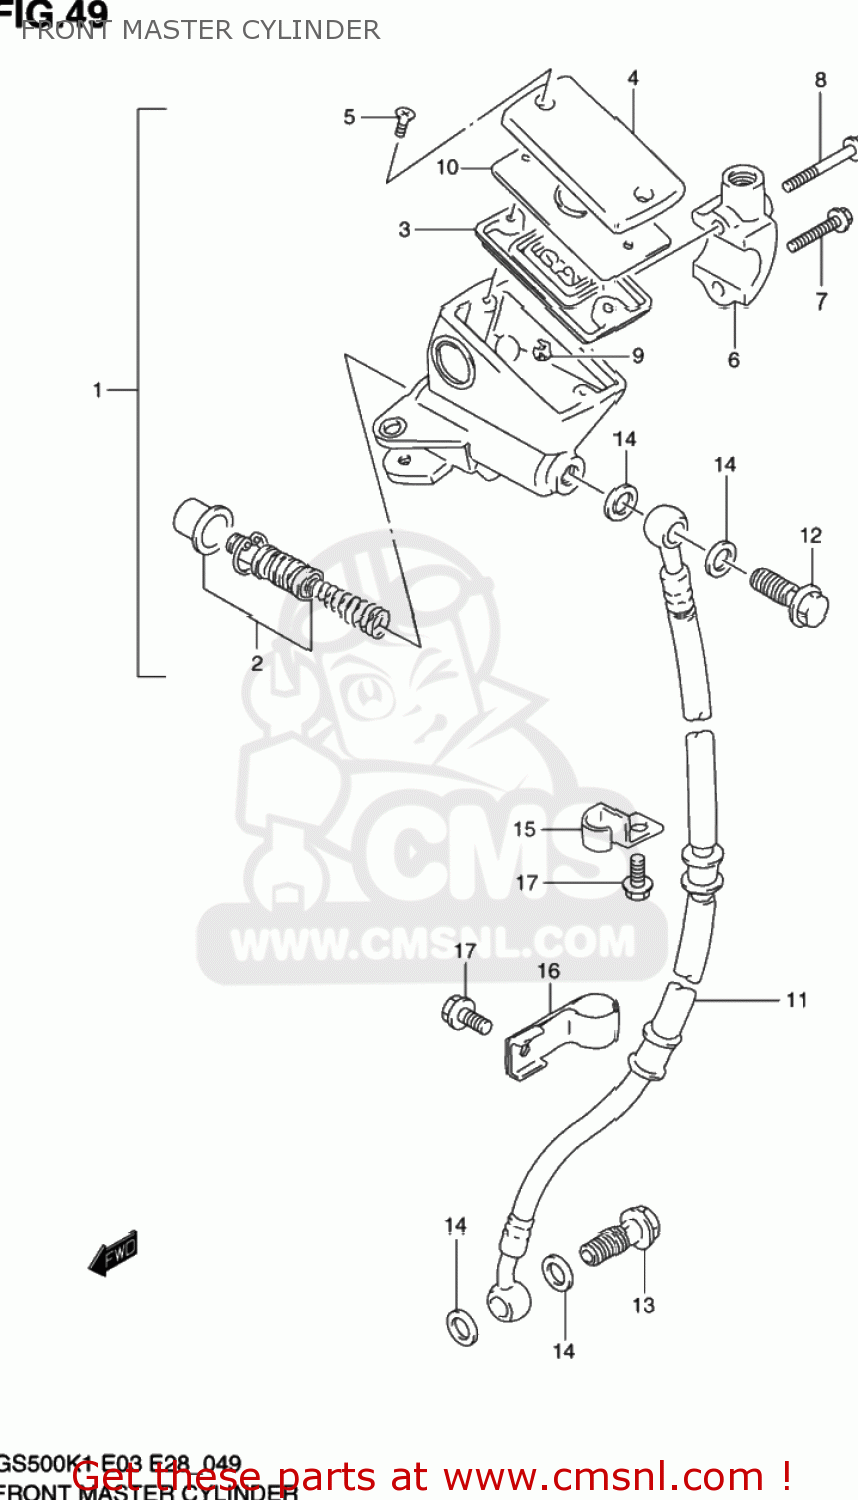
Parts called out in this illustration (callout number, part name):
1	CYLINDER ASSY,FR MASTER
2	PISTON/CUP SET
3	4
4	CAP
5	SCREW
6	HOLDER
7	BOLT(6X25)
8	BOLT(6X38)
9	PROTECTOR
10	PLATE,DIAPHRAGM
11	HOSE,FR BRAKE,R
12	BOLT UNION
13	BOLT UNION
14	WASHER(10X15X1.5)
15	CLAMP,FR BRAKE HOSE
16	CLAMP,FR BRAKE HOSE NO.2
17	BOLT
